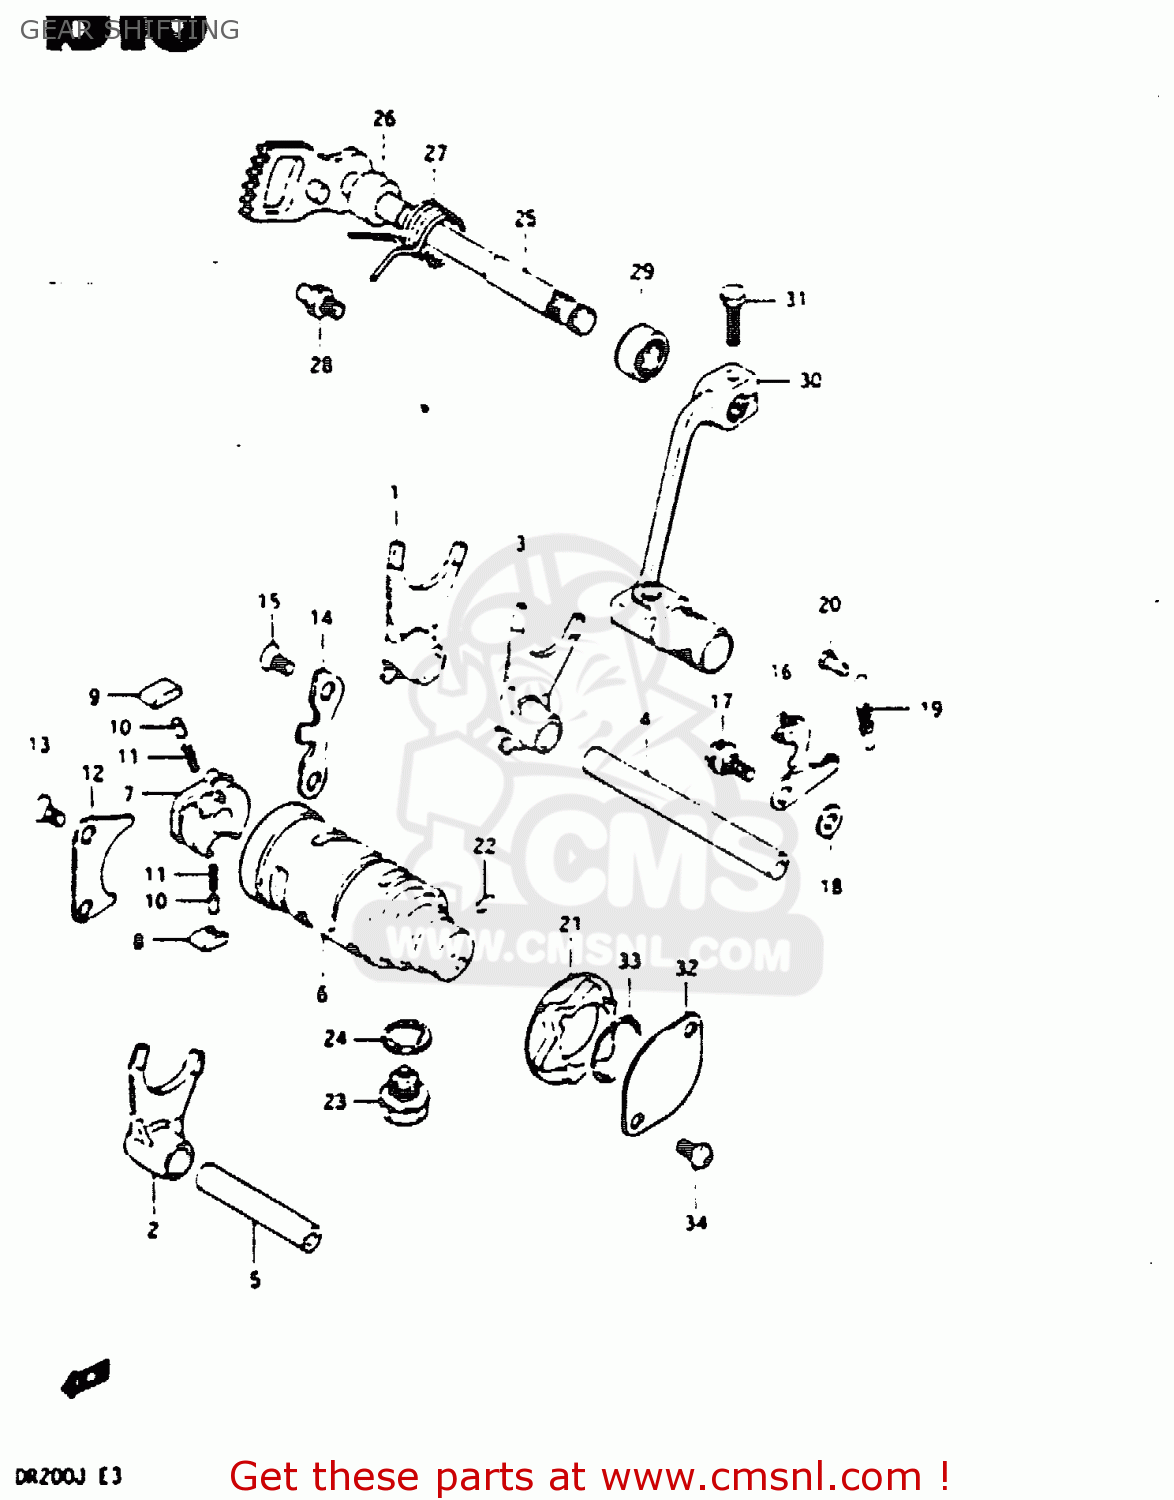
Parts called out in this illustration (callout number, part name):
1	FORK,GEAR SHIFT NO.1
2	FORK,GEAR SHIFT NO.2
3	FORK,GEAR SHIFT NO.3
4	SHAFT,GEAR SHIFT FORK(L:109)
5	SHAFT,GEAR SHIFT FORK
6	CAM,GEAR SHIFT
7	GEAR,GEARSHIFT CAM DRIVE
8	PAWL,GEAR SHIFT NO.1
9	PAWL,GEAR SHIFT NO.2
10	PIN(5X8)
11	SPRING
12	LIFTER,GEAR SHIFT POLE
13	SCREW
14	GUIDE, CAM
15	SCREW
16	STOPPER COMP,GEAR SHIFT
17	BOLT
18	WASHER
19	SPRING
20	RIVET
21	PLATE,GEAR SHIFT CAM STOPPER
22	PIN 4X6
23	PLUG (14X12)
24	GASKET(14X19.2X2) (NAS)
25	SHAFT,GEAR SHIFT
26	SPACER(12X20X15.3)
27	SPRING
28	STOPPER,GEAR SHIFT CAM
29	OIL SEAL
30	LEVER ASSEMBLY,GEAR SHIFTING
31	BOLT
32	CAP,GEAR SHIFT CAM PIVOT
33	O-RING (D:2.4 ID:22.2)
34	SCREW
